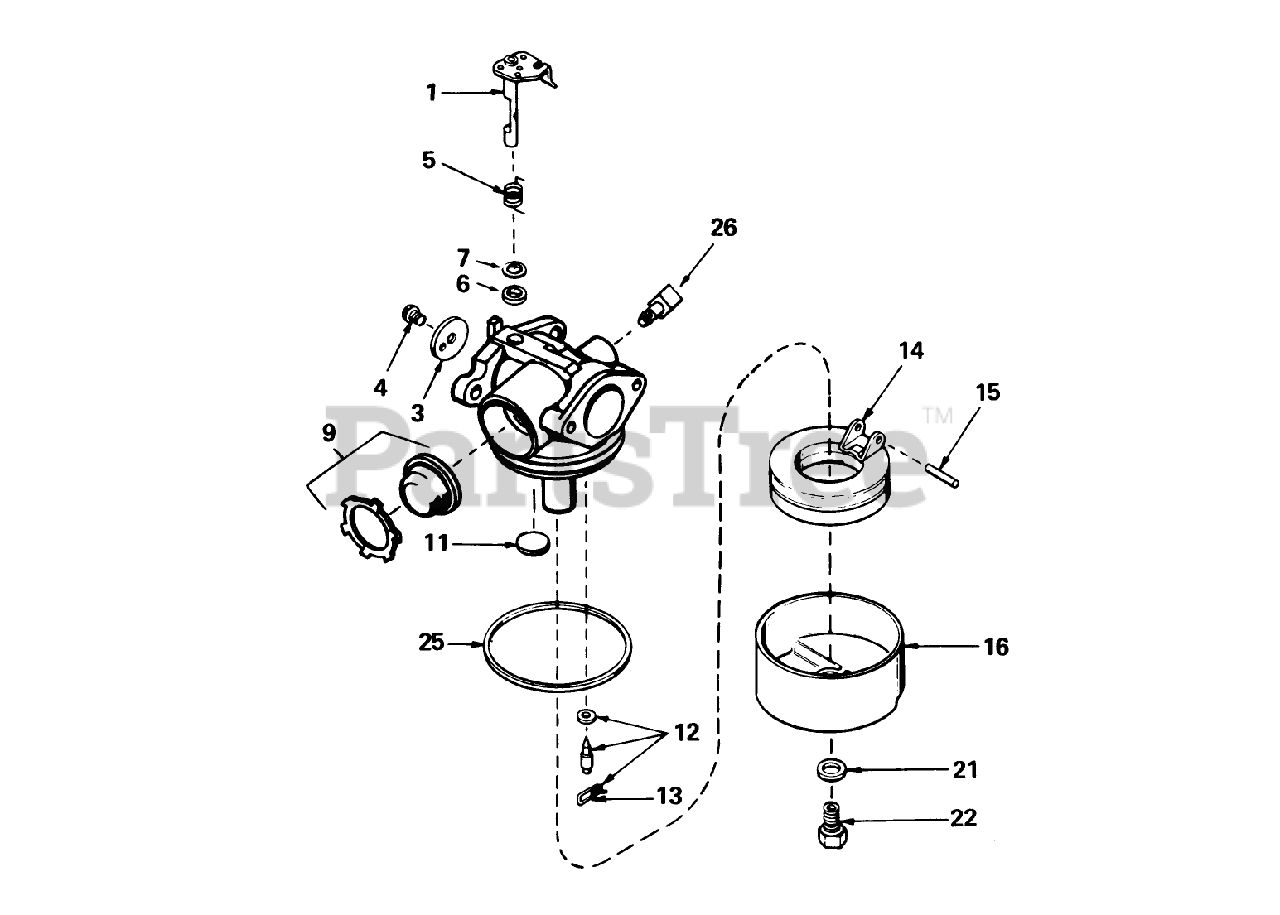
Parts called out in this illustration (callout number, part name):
1	Throttle Shaft and Lever ASM
3	Throttle-Shutter
4	Screw-Shutter
5	Spring-Return, Throttle
6	Seal-Dust
7	Washer-Seal, Dust
9	Primer Assy.
11	Plug-Welch, Atmospheric Vent
12	Inlet Needle, Seat Clip Assy. (Incl. No. 13)
13	Clip-Spring
14	Float
15	Shaft-Float
16	Bowl Float
21	Gasket-Bowl
22	Nut-Float Bowl
25	O Ring-Bowl, Float
26	Fitting-Fuel
